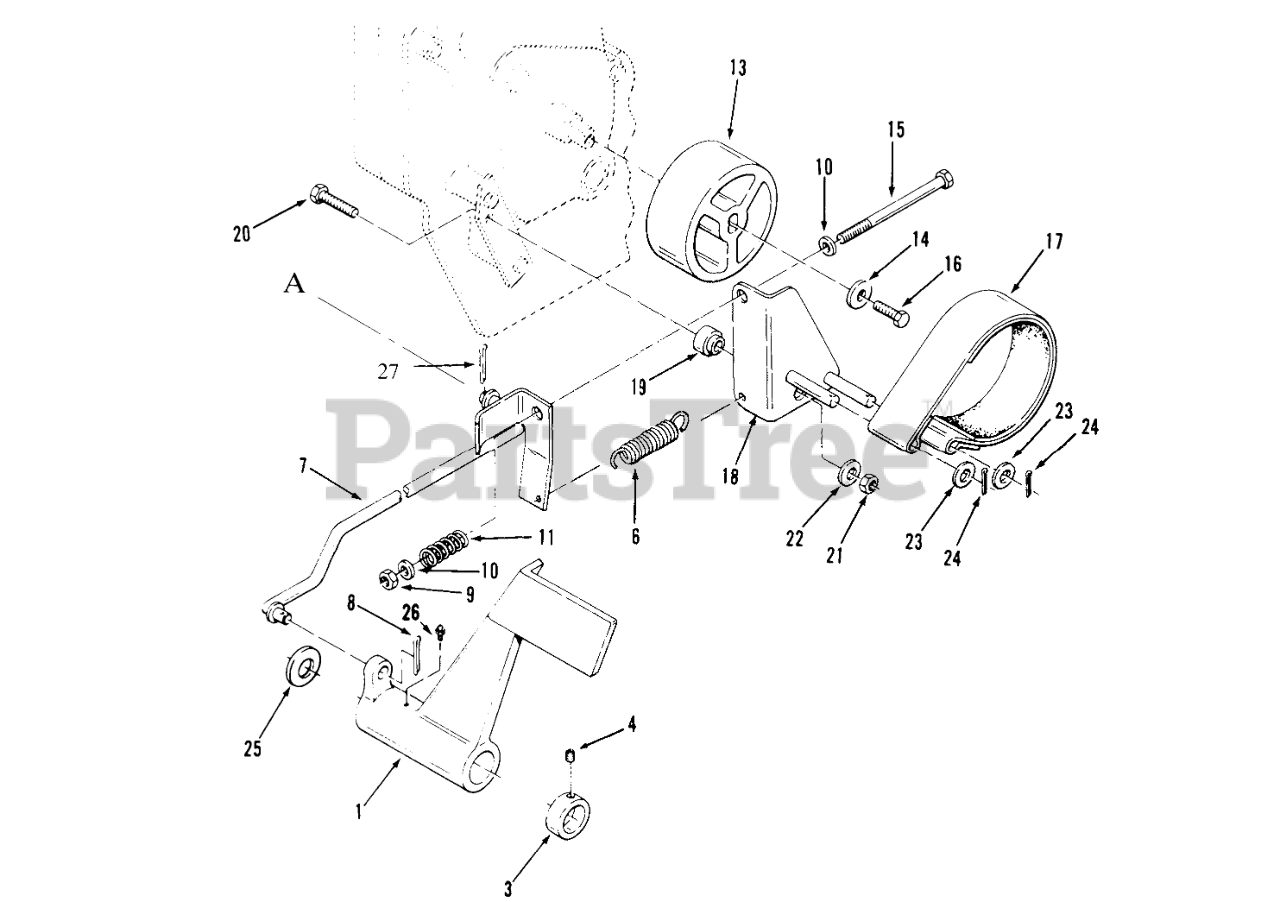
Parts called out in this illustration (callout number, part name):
1	Pedal-Brake
3	COLLAR
4	SCREW-HSH
6	SPRING
7	ASY BRAK RD WAR
8	PIN-COTTER
9	NUT-LOCK, NI
10	WASHER-FLAT
11	SPRING-COMPRESSION
13	DRUM-BRAKE
14	WASHER
15	SCREW-HH
16	SCREW-HH, LOCK
17	ASSY-BRAKE BAND
18	WA-BRAKE PIVOT B
19	BUSHING-BRAKE PIVOT
20	SCREW-HH
21	NUT-LOCK, NI
22	WASHER-FLAT
23	WASHER-FLAT
24	PIN-COTTER
25	WASHER
26	FITTING-GREASE
27	Hairpin
